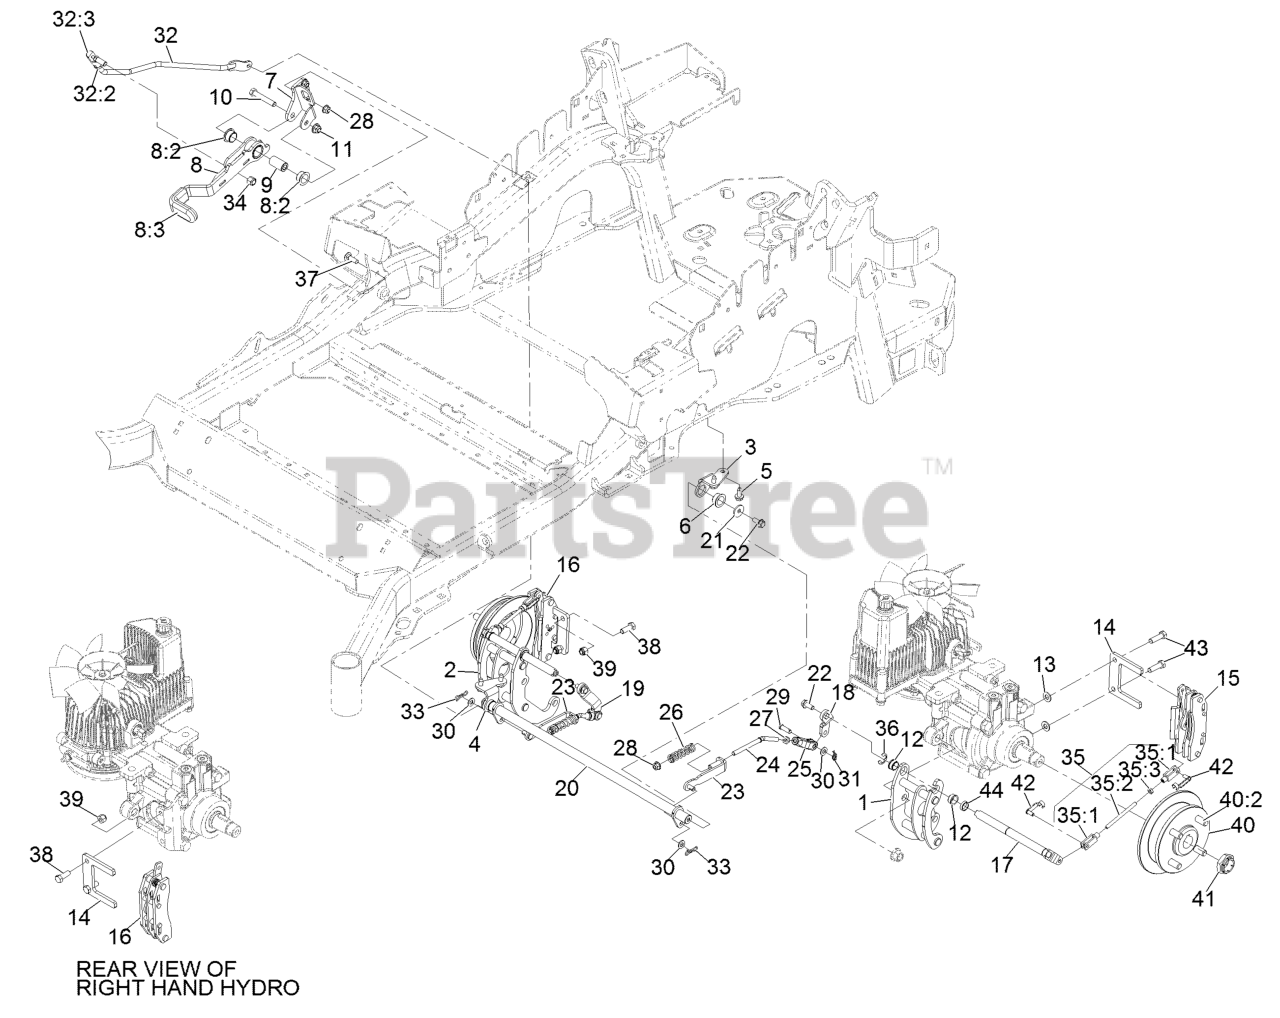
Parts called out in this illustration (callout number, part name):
1	Mount-Bellcrank, LH
2	Mount-Bellcrank, RH
3	Mount-Pivot, LH
4	Mount-Pivot, RH
5	Screw-HWH 5/16-18 X 3/4 Tf
6	Bushing-Flanged
7	Bracket-Mount
8	Brake Lever ASM
8:2	Bushing-Flanged
8:3	Grip-Lever
9	Handle-Pivot, Brake
10	Screw-HH 3/8-16 X 2 1/4
11	Nut-Nyloc 3/8-16 Flg
12	Bushing-Igus
13	Washer-3/8 Sae
14	Plate-Mount, Brake
15	Caliper-Brake
16	Caliper-Brake, RH
17	Bellcrank
18	Arm-Inner, LH
19	Arm-Inner, RH
20	Shaft-Cross
21	Washer-Flat
23	Bracket-L
24	Linkage-Mid
25	Yoke-Offset
26	Spring-Compression
27	Nut-Jam 5/16-24
28	Nut-Nyloc 5/16-18 Flg
29	Pin-Clevis 5/16 X 1 49/64
30	Washer-5/16 Sae
31	Pin-Cotter, Locking
32	Front Linkage ASM
32:2	End-Tie Rod, RH
32:3	Nut-Jam 3/8-24
33	Pin-Cotter, Locking
34	Nut-Nyloc 3/8-24
35	Rear Linkage ASM
35:1	Yoke
35:2	Linkage, Rear
35:3	Nut-Jam 1/4-28
37	Bolt-Carriage 5/16-18 X 1
38	Screw-HH 3/8-16 X 1
39	Nut-Nyloc 3/8-16
40	Wheel Hub ASM
40:2	Stud-Wheel
41	Locknut
42	Pin-Clevis, Spring
43	Screw-HH 3/8-16 X 1 1/4 Patch Lock
